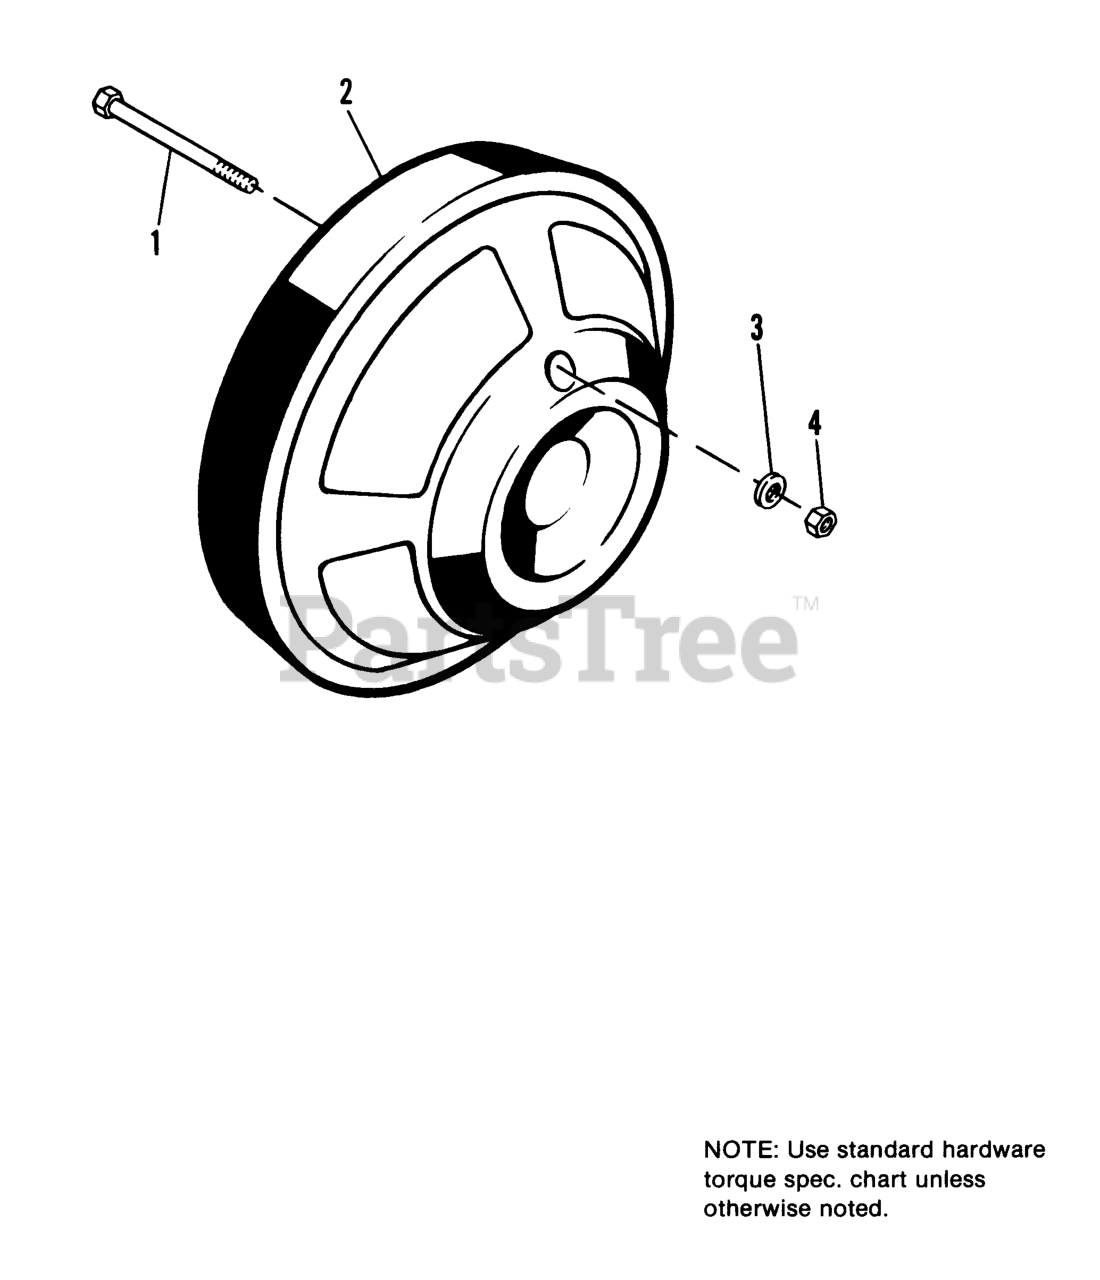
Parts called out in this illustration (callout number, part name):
1	CAPSCREW, Hex Hd., 3/8-16 x 8-3/4 (2-1/2 ThreadHOSE, Fuel, Cut to 12th)
2	WEIGHT, Wheel Kit
3	WASHER, 3/8
4	NUT, Hex, 3/8-16
